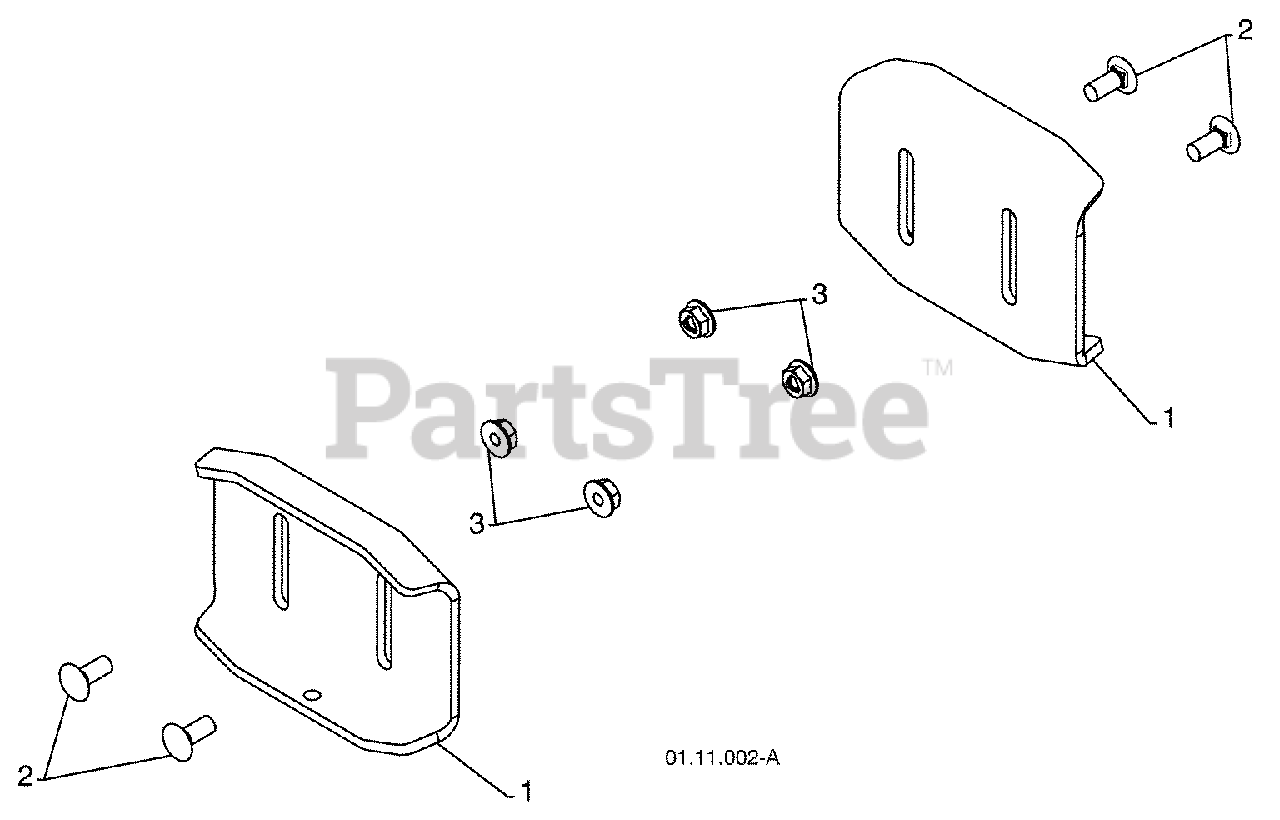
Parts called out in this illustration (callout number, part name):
1	SKID PLATE
2	CARRIAGE BOLT 5/16-18 X .750
3	NUT 5/16-18
